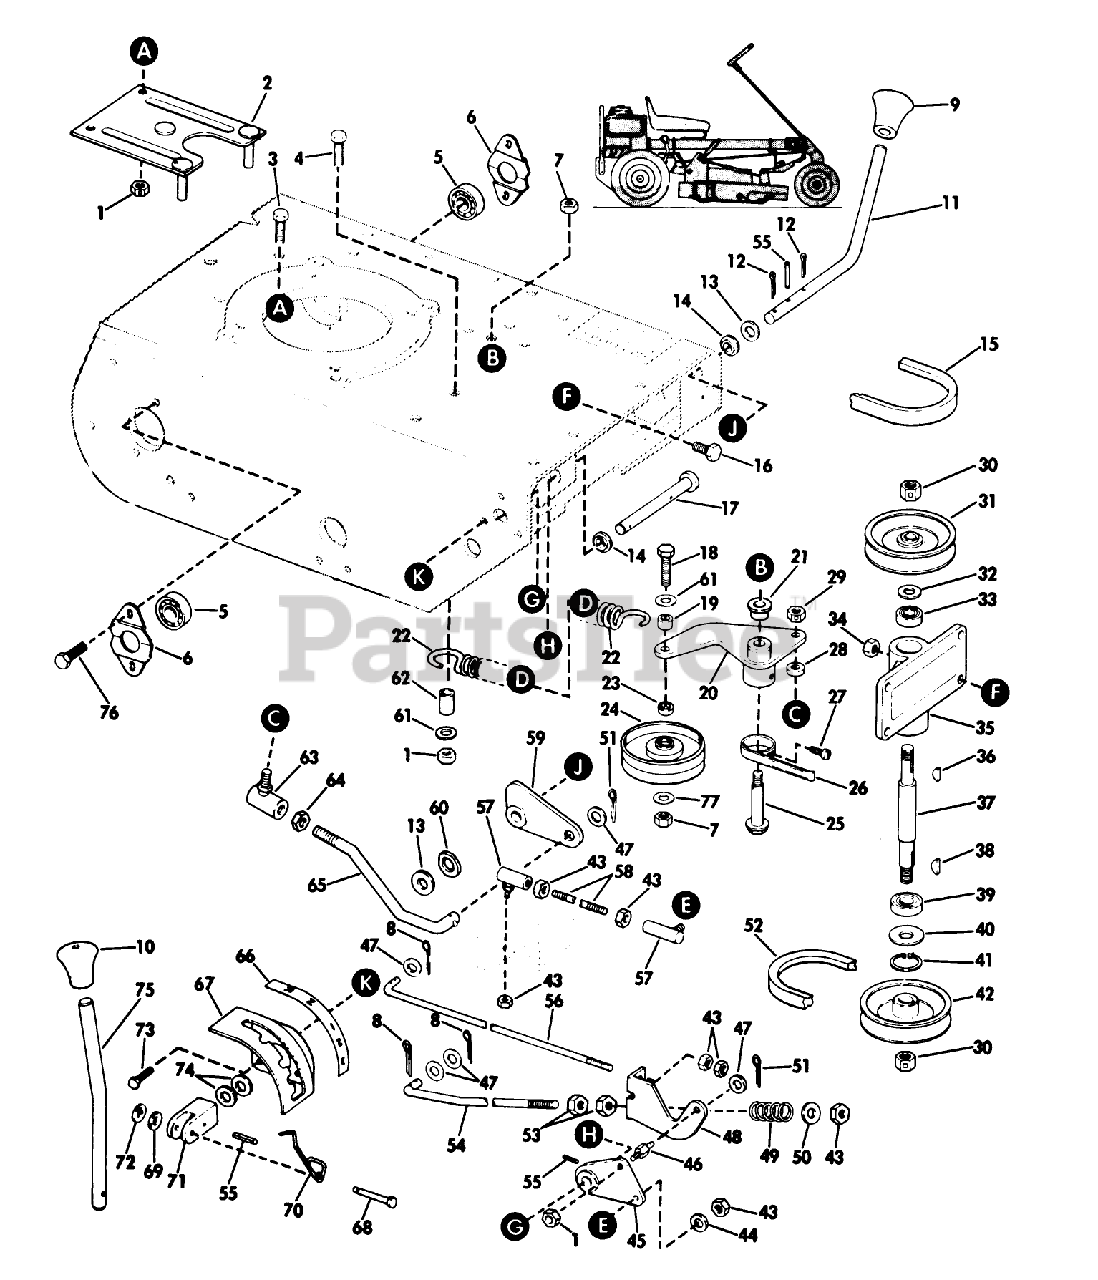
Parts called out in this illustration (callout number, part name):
7	LOCKNUT
12	Cotter Pin
20	Hub and Bell Arm Assembly
43	STOP NUT
53	STOP NUT
